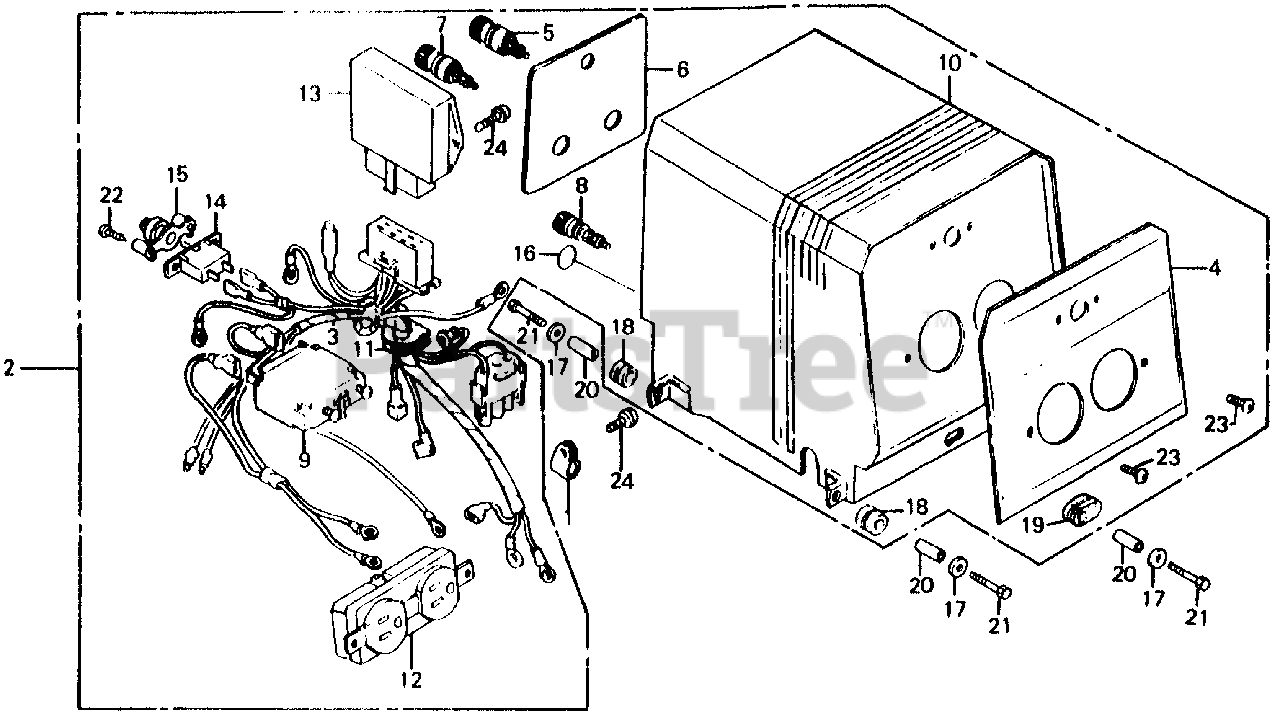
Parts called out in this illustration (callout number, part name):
1	CLAMP B, CABLE
2	BOX ASSY., CONTROL *R8* (BRIGHT RED)
3	WIRE HARNESS ASSY.
4	MARK, SWITCH PANEL
5	TERMINAL, D.C. OUT (+)
6	MARK, RR. PANEL
7	TERMINAL, D.C. OUT (-)
8	TERMINAL ASSY., GROUND
9	BREAKER, CIRCUIT (11.5A) (NOT AVAILABLE)
10	BOX, CONTROL *R8* (BRIGHT RED)
11	GROMMET, WIRE
12	RECEPTACLE (125V-15A)
13	REGULATOR ASSY., AUTOMATIC VOLTAGE
13	REGULATOR ASSY., AUTOMATIC
14	PROTECTOR, CIRCUIT (DC)
15	LENS ASSY., PROTECTOR
16	MARK, GROUND
17	WASHER, FLAT (20MM)
18	RUBBER, CONTROL BOX
19	RUBBER, CONTROL BOX
20	COLLAR, CONTROL BOX (NOT AVAILABLE)
21	BOLT, HEX. (6X25)
22	SCREW, PAN (3X12)
23	SCREW, PAN (4X6)
24	SCREW-WASHER (5X12)
